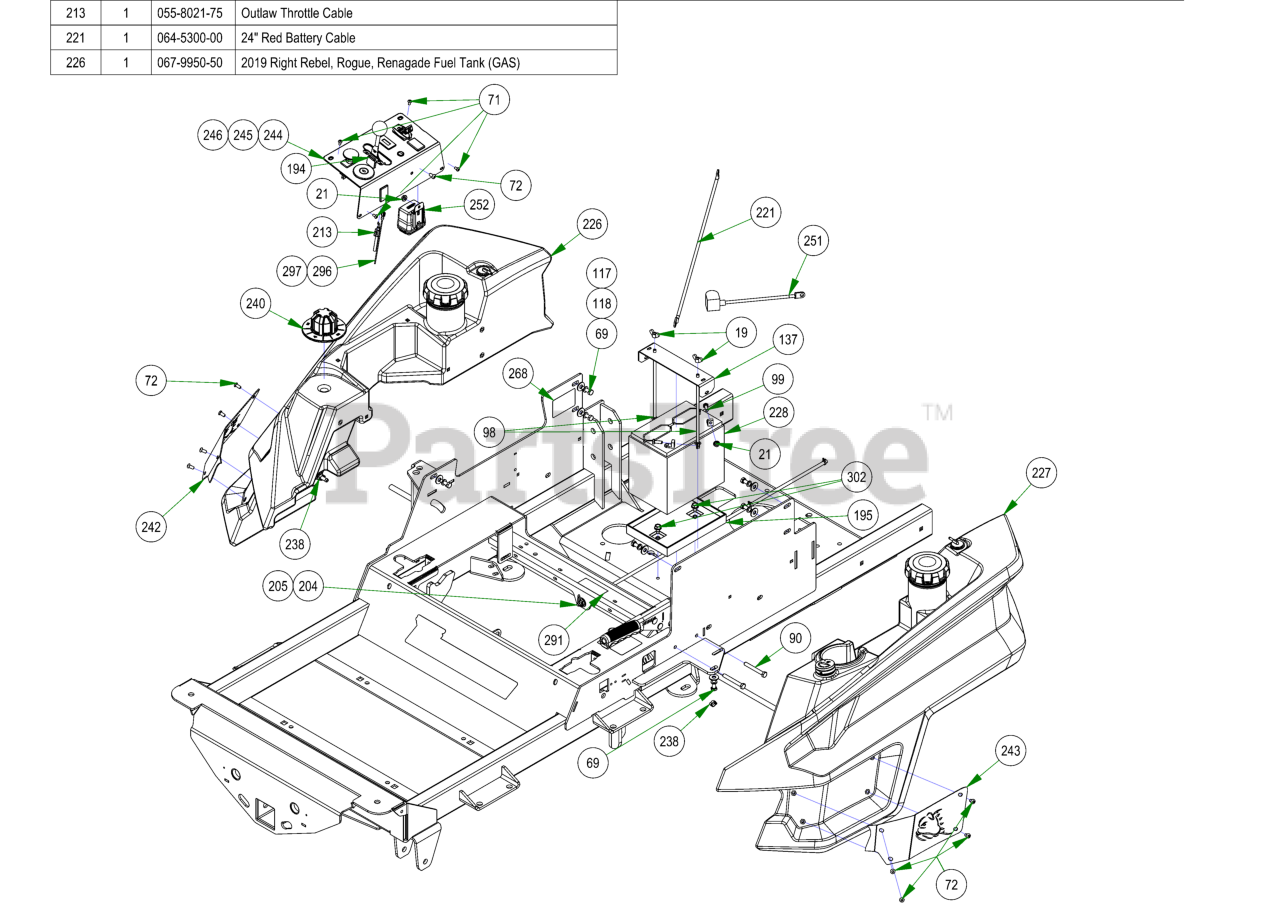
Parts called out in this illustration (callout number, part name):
19	1/4-20 WING NUT FORGED (TYPE A) LIGHT SERIES ZINC
21	1/4-20 HEX SERRATED FLANGE NUT HARD/ZINC
69	5/16-18 X 1 HEX CAP SCREW (GR.5) ZINC
71	10-32 X 3/8 BUTTON SOCKET CAP SCREW 18-8 STAINLESS STEEL
72	1/4-20 X 1/2 BUTTON SOCKET CAP SCREW 18-8 STAINLESS
90	5/16-18 X 2-1/2 HEX CAP SCREW (GR.5) ZINC
98	1/4-20 X 8 CARRIAGE BOLT (MIN 6" THREAD) ZINC
99	1/4-20 X 3/4 HEX CAP SCREW (GR.5) ZINC
117	5/16 USS FLAT WASHER (7/8 OD) ZINC
118	5/16 SPLIT LOCKWASHER ZINC
137	2023 Rogue Battery Hold Down Plate
194	Ignition Key
195	Battery Tray
204	2023 Rebel Rogue Renegade Fuel Line for Kohler
205	2023 Rebel Rogue Renegade Fuel Line for Kawasaki
213	Outlaw Throttle Cable
221	24" Red Battery Cable
226	2019 Right Rebel, Rogue, Renagade Fuel Tank (GAS)
227	2019 Left Rebel, Rogue, Renegade Fuel Tank (GAS)
228	SP-35 Battery
235	2023 Rogue Frame - Painted
238	2 EAR CLAMP 12.5mm-15mm
240	2019 Deck Height Dial
242	2019 Outlaw Fuel Tank Insert - Right
243	2019 Outlaw Fuel Tank Insert - Left
244	Rebel/Rogue EFI Control Panel Assy
245	Rebel/Rogue Control Panel Assy
246	Rebel/Rogue Control Panel Assy-Drive by Wire
251	Starter Cable
252	2019 Wiring Harness-Rebel/Rogue
268	Hydraulic Decal
281	2019 Rogue Cooler Cover Decal
291	R-Series Shut Off Valve Decal
296	16 AWG Black Insulated Wire for Tachometer
297	1/4" Female Quick Connect Terminal
302	5/16-18 X 1/2 HWH unslot (F) tcs zinc
